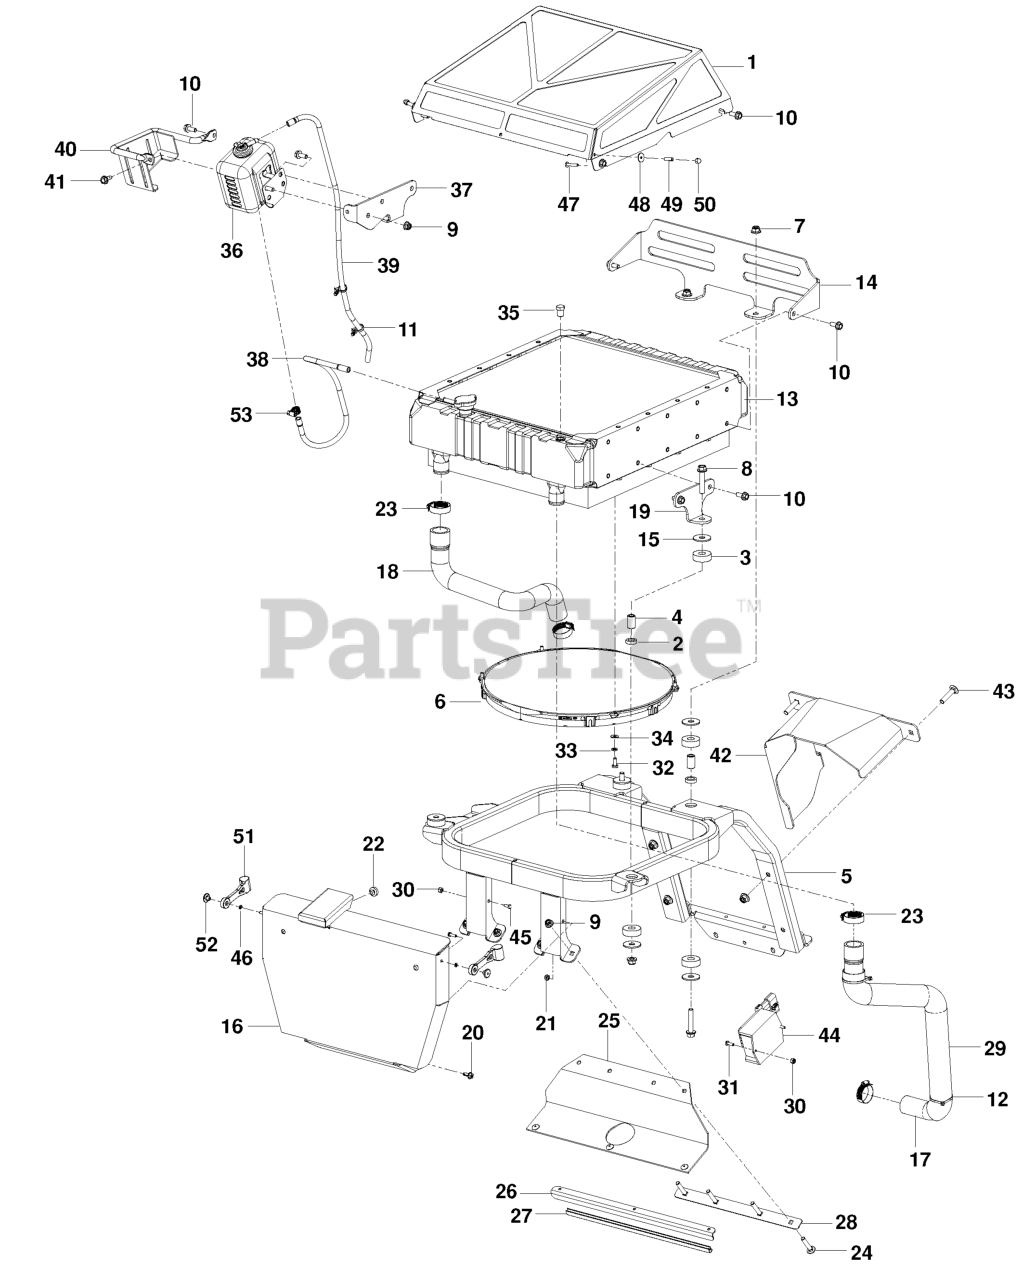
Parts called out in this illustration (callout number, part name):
1	SCREEN, DEBRIS, BLK
2	ISO-MOUNT INSERT
3	ISO-MOUNT BUSHING
4	ISO MT. BUSHING
5	MOUNT, RADIATOR, GRAY
6	FAN, ELECTRIC
7	NUT 3/8-16 HEX FLG NYLOC ZD
8	HHFS 3/8-16 X 2.0 GD 5
9	5/16-18 NYLOC FLANGE NUT
10	HHFS 5/16-18 X 3/4
11	TIE WRAP, 8-3/8", W/CLIP
12	TIE, PLASTIC
14	MOUNT, RADIATOR, REAR-BLK
15	7/16 HD FLAT WASHER
16	GUARD, HOSE W/DECALS
17	HOSE, RADIATOR, LT
18	HOSE, RADIATOR, RT
19	MOUNT.RADIATOR.FRONT.BLACK
20	SCREW- 1/4-20 X 5/8
21	JAM NUT 1/4C (2 2 PW01)
22	GROMMET, BUMPER
24	RHSNB 5/16-18X1 3/4
25	GUARD, BELT
26	STRAP, BELT GUARD, BLK
27	RP.FLEX TRIM, BLK-LENGTH 1 FT
28	STRAP, GUARD
29	SLEEVE, HOSE
30	NUT 10-24 NYLOC
31	SCREW #10-24 X 5/8
32	HCS 1/4C X 5/8
33	LOCKWASHER 1/4"
34	WASHER 1/4 SAE
35	FITTING, PIPE, 1/4 NPT
36	BOTTLE, OVERFLOW
37	MOUNT, RADIATOR, BLK
38	HOSE, OVERFLOW, UPPER
39	HOSE, OVERFLOW, LOWER
40	GUARD, OVERFLOW, BLK
41	BOLT 5/16-18 X 3/4
42	SHIELD, BELT W/DECAL - GR
43	RHSNB 3/8-16X1-3/4
44	MODULE, FAN REVERSE
45	HCS #10-24 X 1/2
46	WASHER - 3/16 LOCK ZD
47	SCREW #10-24 X 1-1/8 ZD SPEC
49	BSHG .202X.75 LG SPLIT ZD SPEC
50	NUT 10-24 ACORN ZD
51	HOOD LATCH
52	NUT 10-24 WELD PLATED
53	CLAMP, WORM GEAR, NO. 4
